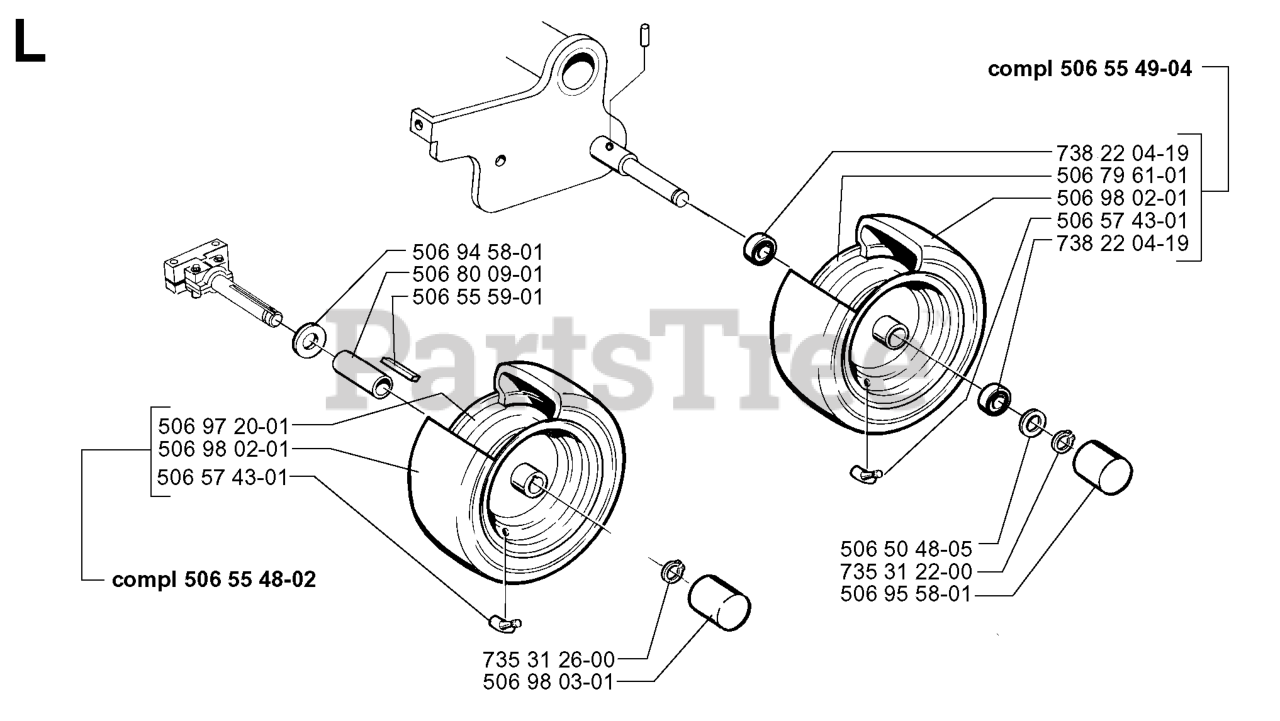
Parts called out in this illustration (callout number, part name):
1	DECAL.FENDER.WARNING
2	DECAL.MOWER
3	DECAL.WARN.KEEP.HAND.AWAY
4	DECAL.WARNING.CUST.RESP.E85.
5	LABEL.EPA.COMPLIANCE
8	DECAL.MOWER.SCH.48/54
9	DECAL BTRY SYMBOLS
14	DECAL.SDPNL.GT2.LGT24K54.668
16	DECAL.BADGE.170MM.TEXTLOGO.
17	DECAL.RPL.KW.FR691V.TGW.54.K46
